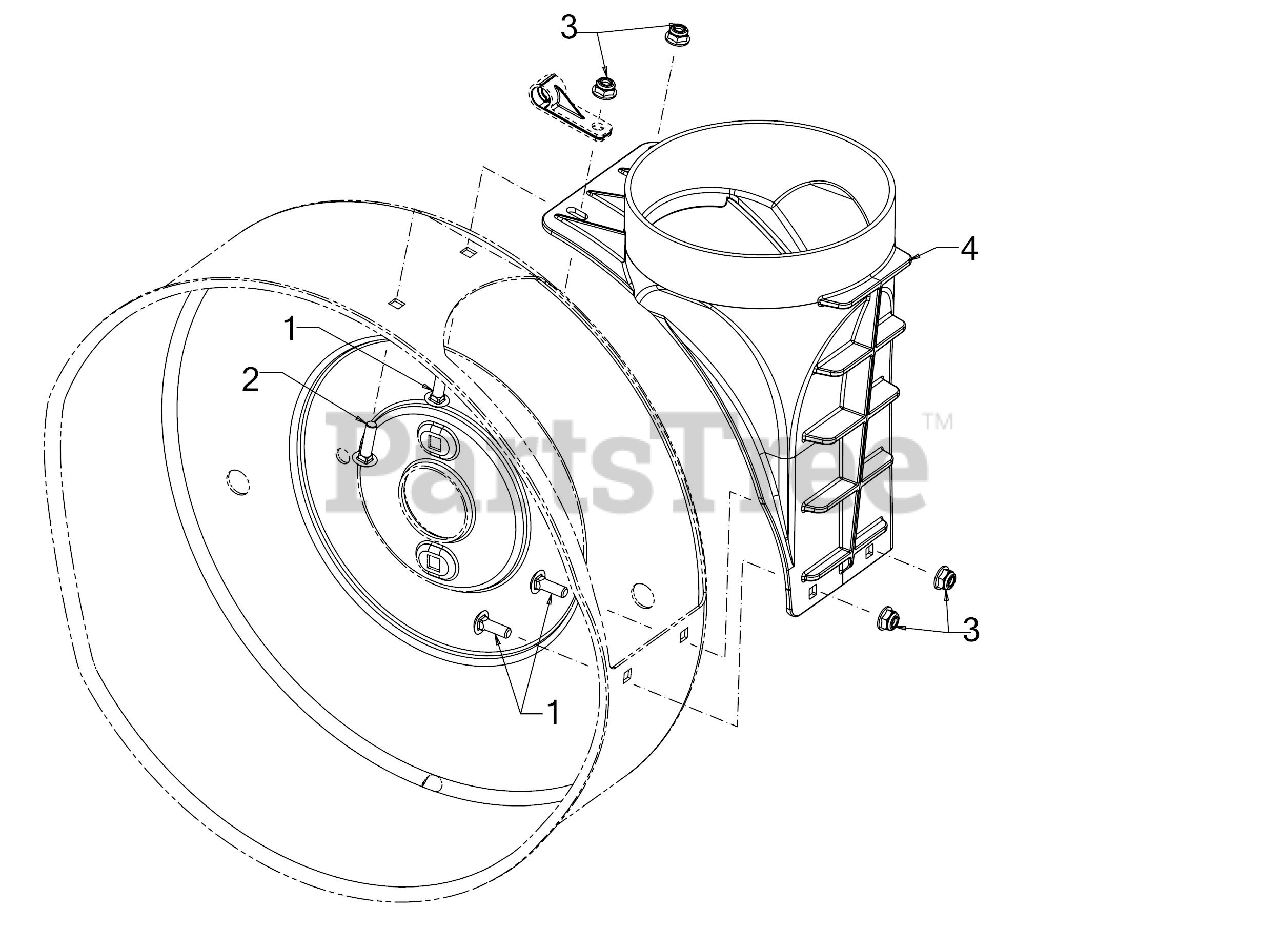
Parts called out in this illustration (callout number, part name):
1	SCREW 1/4-20 x .75 GR5
2	FLANGE LOCK NUT
3	SCREW 1/4-20 x 1 GR5
4	6" CHUTE ADAPTER
